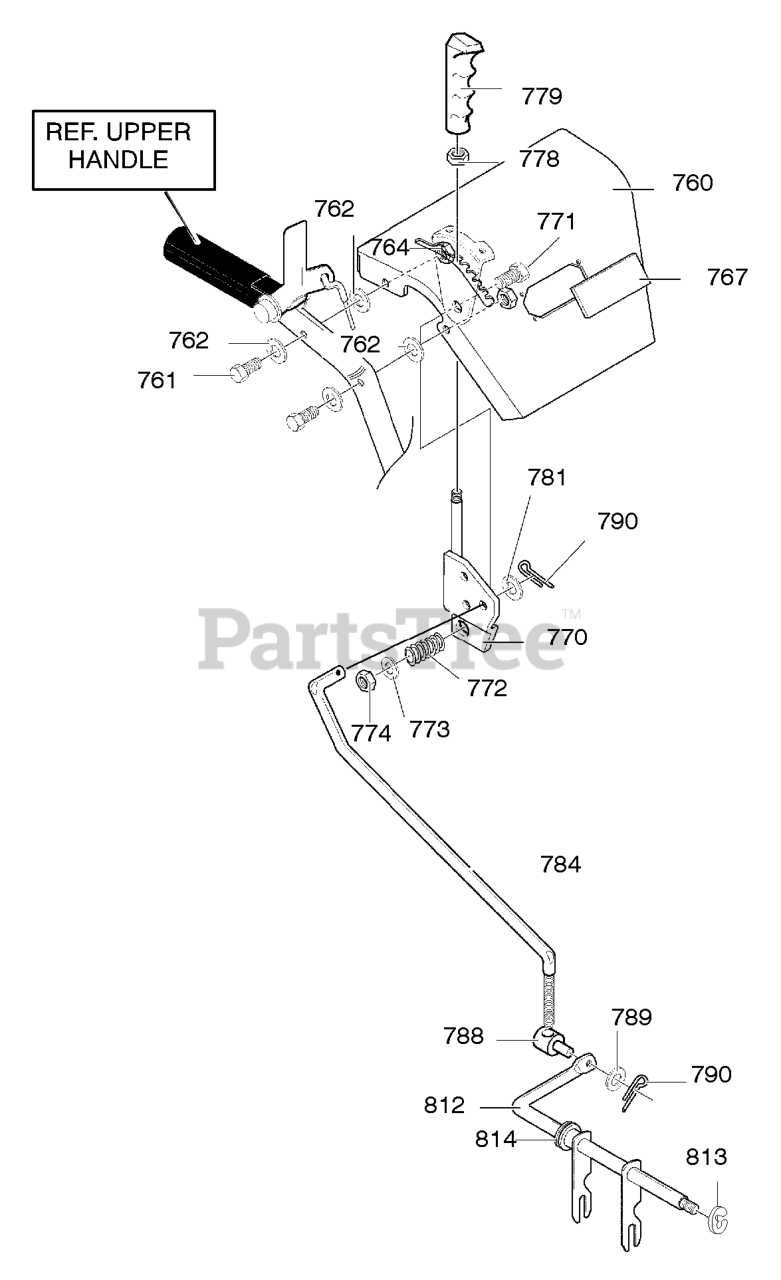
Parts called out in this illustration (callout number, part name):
760	ASSEMBLY, PANEL
761	SCREW, 5/16-18 x 1.75
762	FLATWASHER
764	NUT, 5/16-18 HEXWDFLLK
767	PLATE, BLANKING LIGHT
770	HANDLE ASSY SPD CTRL
771	SCREW 3/8-16X2.00
773	FLATWASHER
774	NUT, 3/8-16 HEXNYL
778	NUT, 3/8-16 REGHEX
779	HANDLE 3/8-16
781	FLATWASHER
784	ROD, SPEED CONTROL
788	NUT, TRUNNION
789	FLATWASHER
789	PIN, COTTER
790	COTTER PIN
812	ROD, ASSY YOKE
813	RING, RETAINER
814	BEARING, FLANGE
